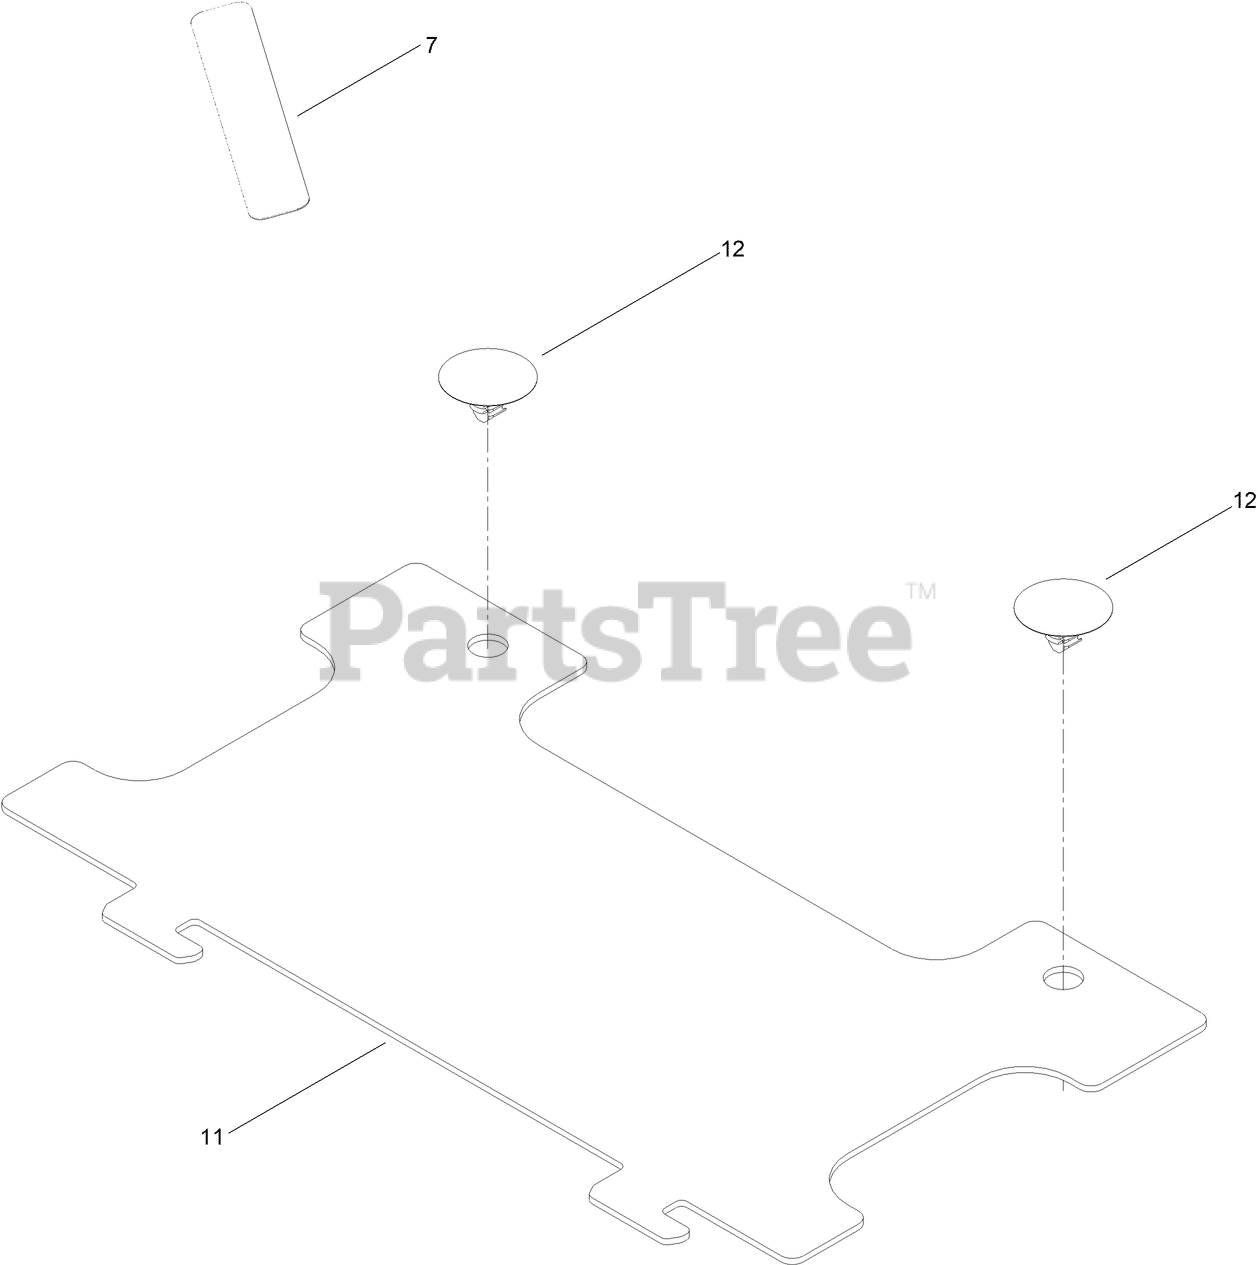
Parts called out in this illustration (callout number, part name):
7	DECAL-SHUTDOWN
11	SHIELD
12	RIVET-PLASTIC
